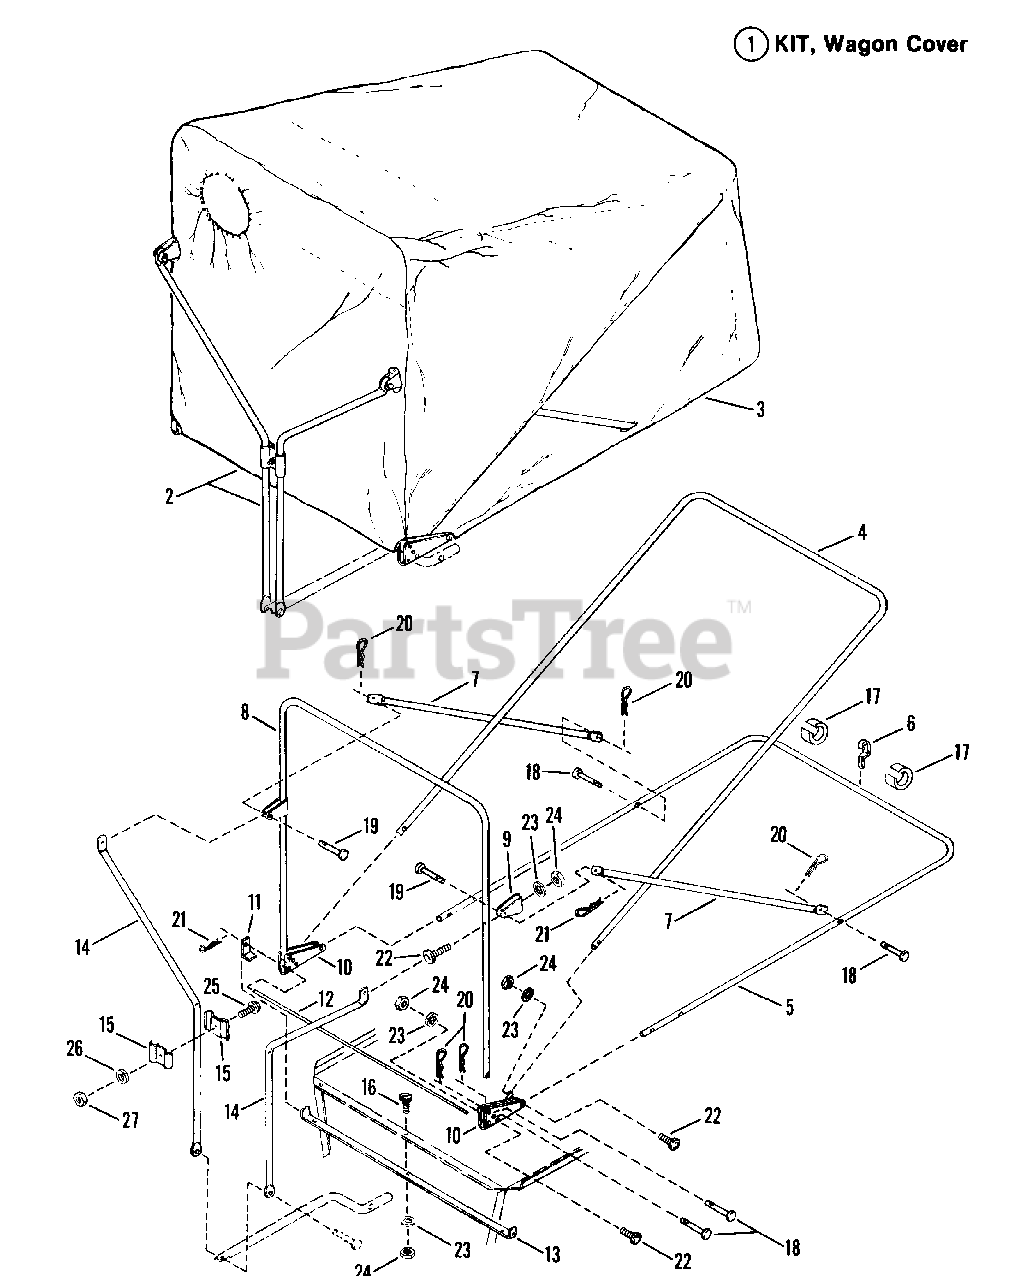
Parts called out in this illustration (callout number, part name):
1	KIT, Wagon Cover
2	FRAME/CANOPY ASSEMBLY
3	CANOPY, Cloth Only
4	FRAME, Center
5	FRAME, Base
6	LOCK, Canopy
7	BRACE, Frame
8	FRAME, Front
9	CLAMP, Rod
10	BRACKET, Corner
11	CLIP, Hinge
12	PIN, Hinge
13	MOUNT, Hinge
14	STRUT, Frame
15	CLAMP, Strut
16	CARRIAGE BOLT, 1/4-20x3/4"
17	BUSHING, Plastic Wear Pads
18	PIN, 1/4x1 1/8" Clevis
19	PIN, 5/16 Clevis
20	PIN, 1/4 Hair
21	PIN, Hair
22	CARRIAGE BOLT, 1/4-20x1"
23	LOCKWASHER, 1/4 Internal Tooth
24	NUT, 1/4-20 Hex
25	CAPSCREW, 3/8-24x1"
26	LOCKWASHER, 3/8 Split
27	NUT, 3/8-24 Hex
